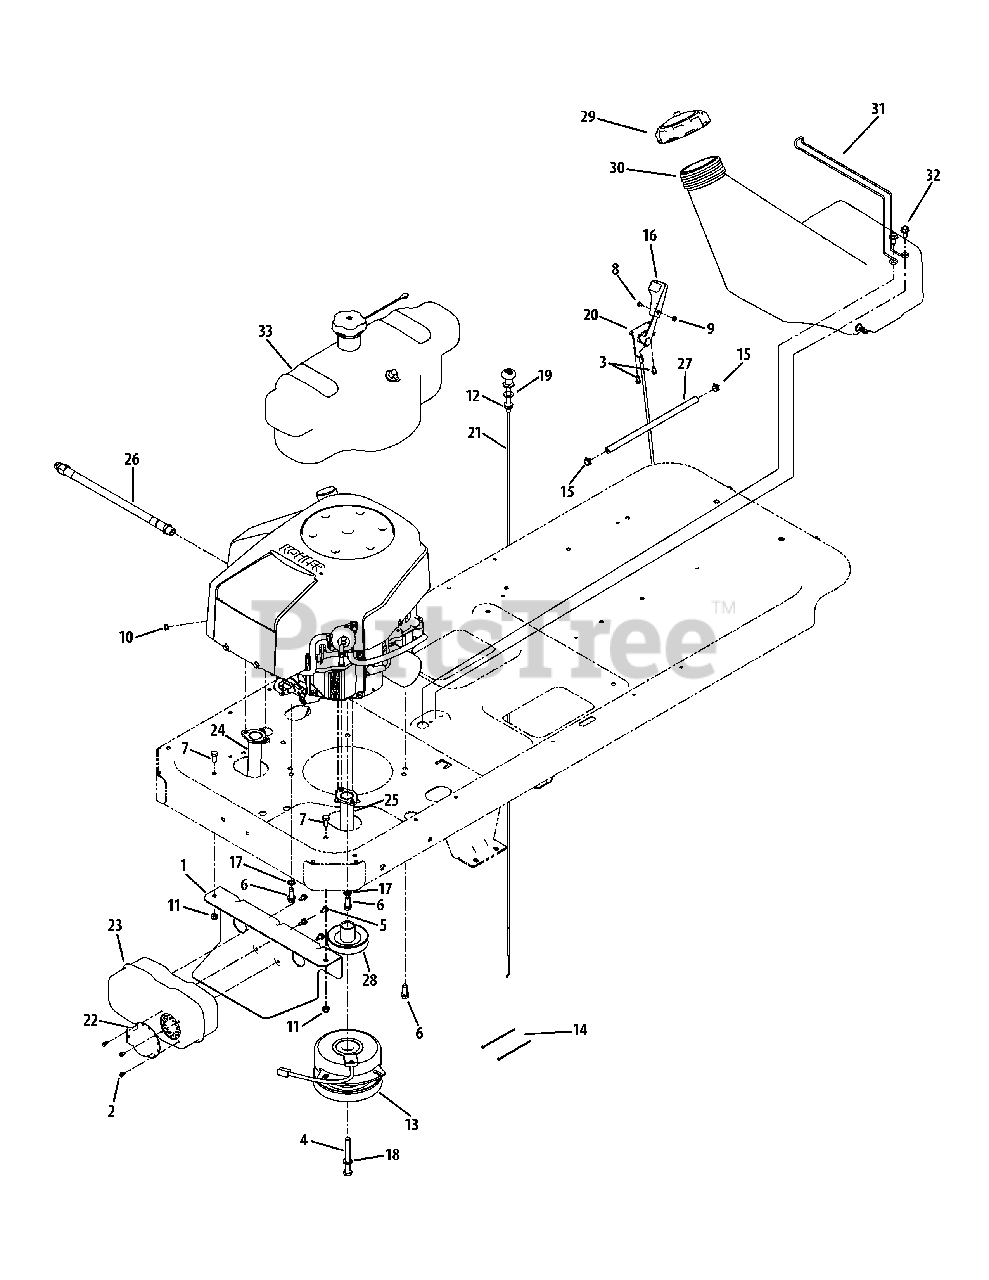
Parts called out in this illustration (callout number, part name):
1	Muffler Mount Bracket
2	Hex Washer Screw, #8-18 x .500
3	Hex Washer Screw, #12-16 x .50
4	Hex Lock Screw, 7/16-20 x 3.50
5	Hex Washer Screw, 1/4-20 x .500
6	Hex Washer Screw, 3/8-16 x 1.000
7	Hex Washer Screw, 5/16-18 x .75
8	Machine Screw, #8-32 x .375
9	Hex Nut, #8-32
10	Sems Nut, 1/4-20
11	Hex Lock Nut, 5/16-18
12	Flange Lock Nut, 3/8-16
13	Electric PTO Clutch
14	Cable Tie
15	Hose Clamp
16	Throttle Control Knob
17	Lock Washer, 3/8
18	Lock Washer, 7/16
19	Flat Washer, .406 x .875 x .059
20	Throttle Cable
21	Choke Cable
22	Muffler Deflector
23	Dual Inlet Muffler
24	Exhaust Pipe, LH
25	Exhaust Pipe, RH
26	Oil Drain Hose
27	Fuel Hose
28	Engine Pulley
29	Fuel Cap
30	Fuel Tank
31	Tank Mounting Wire
32	Hex Washer Screw, 5/16-18 x .750
33	Fuel Tank Assembly
